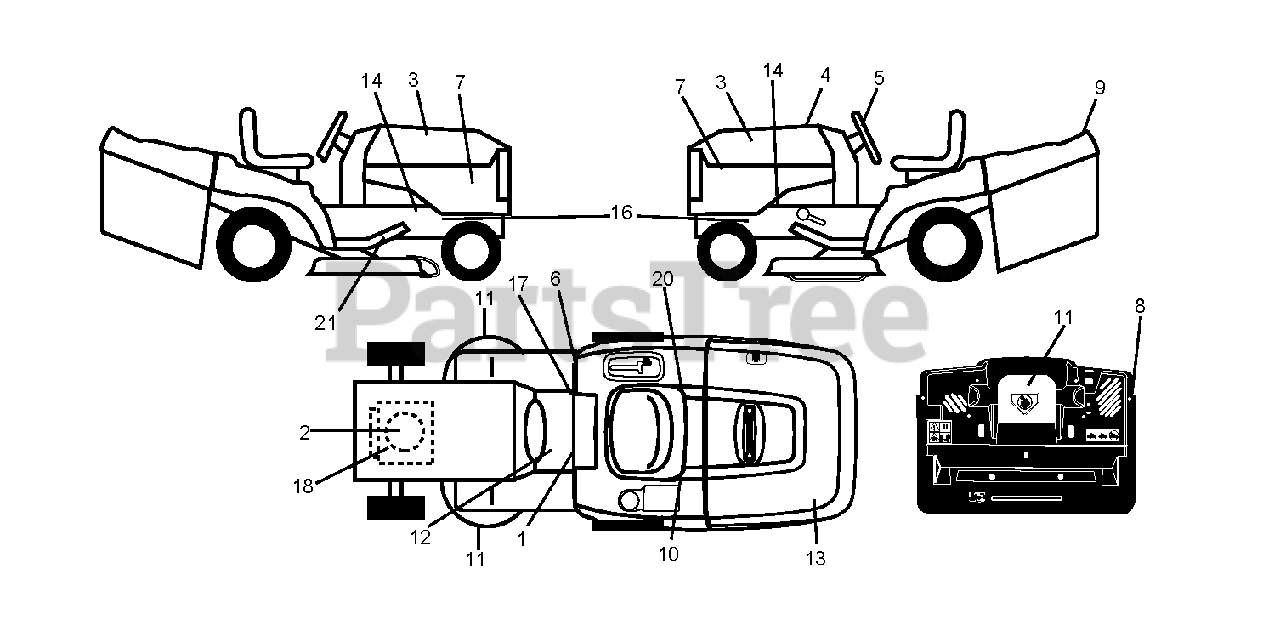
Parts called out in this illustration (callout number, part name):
10	DECAL BTRY SYMBOLS
11	DECAL.INTERNATIONL.CUTFINGER
17	DECAL PARK BRAKE
20	DECAL.BYPASS.FENDER.CRD.LT.YT
